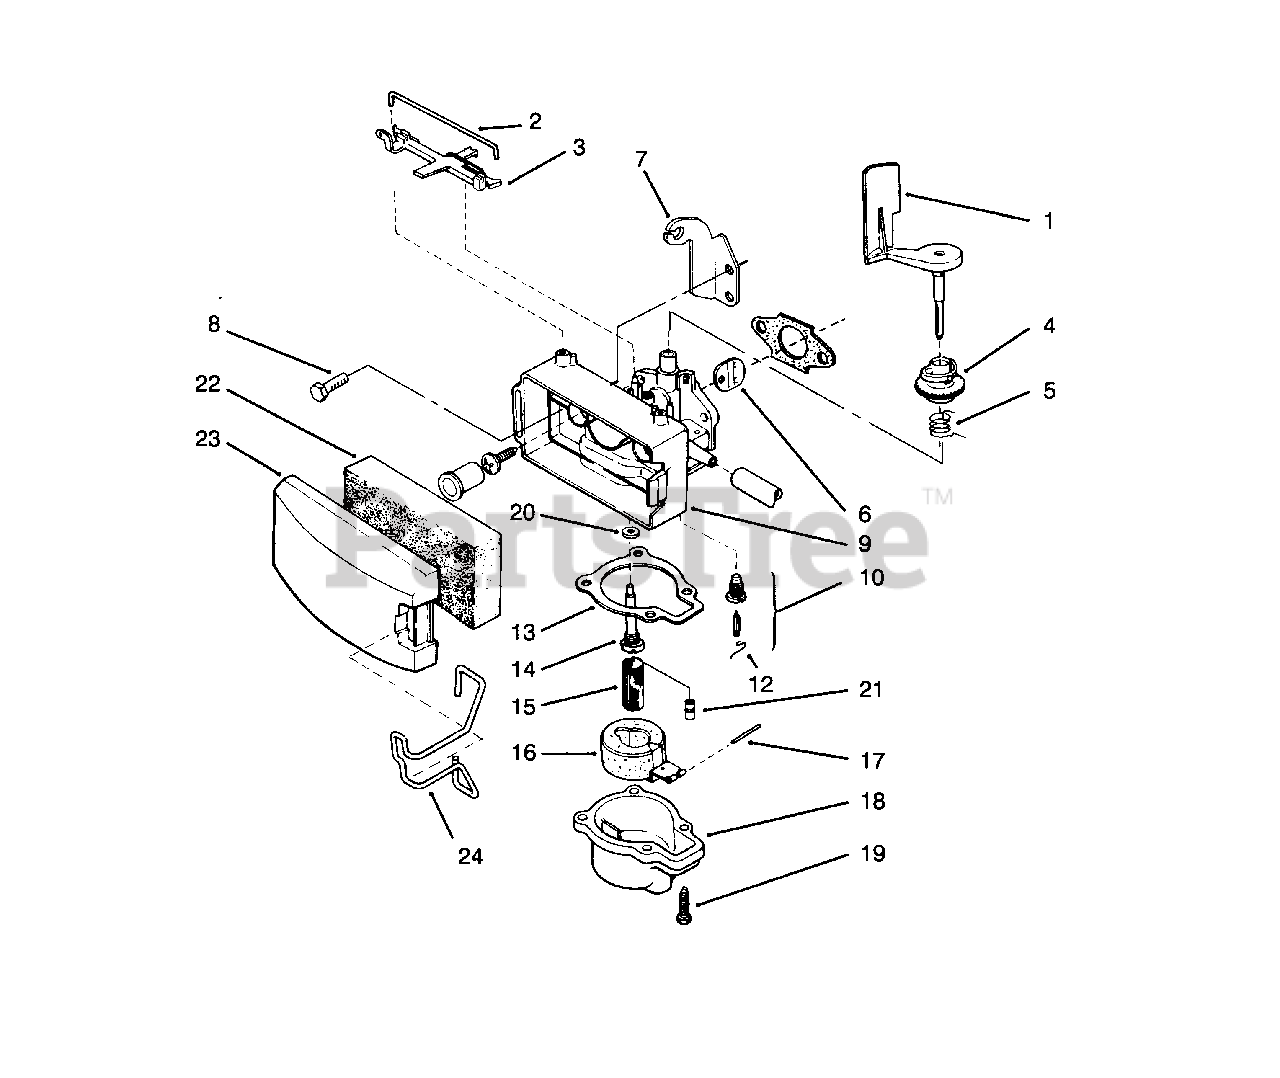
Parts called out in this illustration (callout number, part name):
1	Air Vane & Shaft
2	Retainer-Speed Control
3	Lever-Speed Adjust
4	Collar-Air Vane
5	Spring-Governor
6	Disc-Throttle
7	Bracket-Throttle Control
9	Carburetor Body
10	Kit-Float Valve, Body & Seat (Incl. Ref. #12)
12	Spring
13	Gasket
15	Filters-Fuel
16	Float & Arm Assembly
18	Float Chamber
21	Main Jet
22	Filter
23	Cover
24	Retainer
